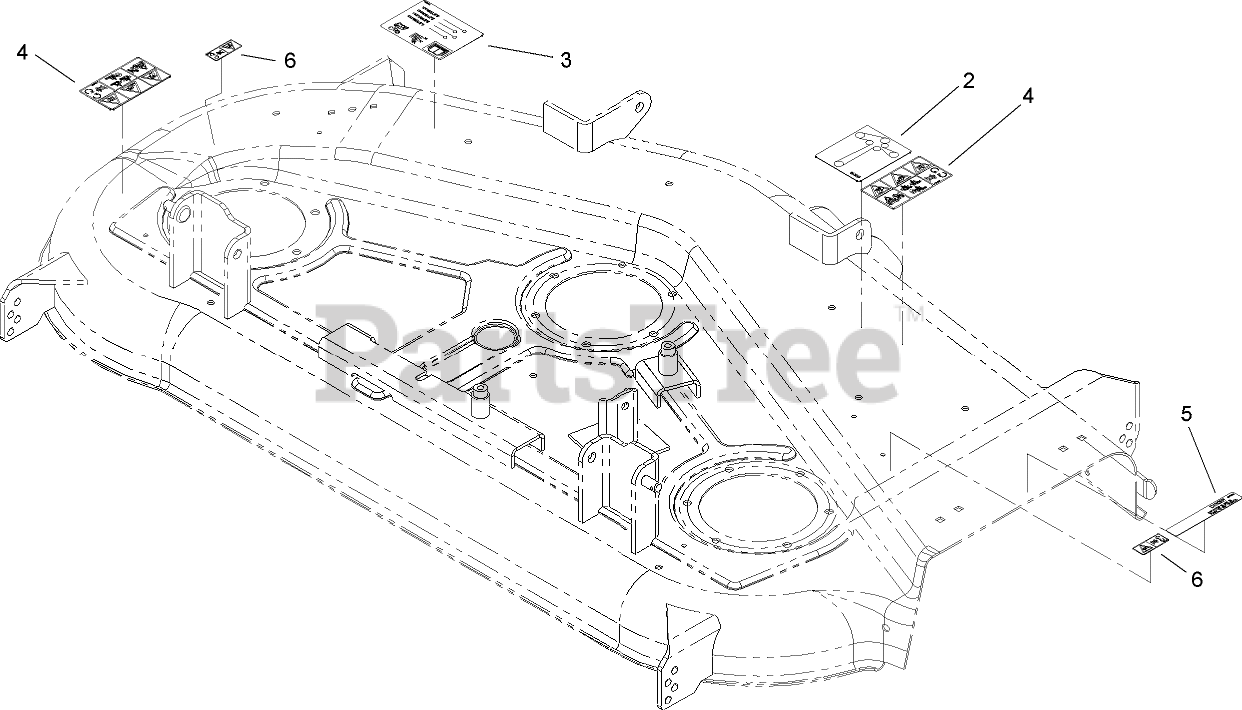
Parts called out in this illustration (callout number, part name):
2	DECAL-ROUTING, BELT
3	DECAL-SCALP, ANTI
4	DECAL-DANGER
5	DECAL-DANGER
6	DECAL-DANGER
